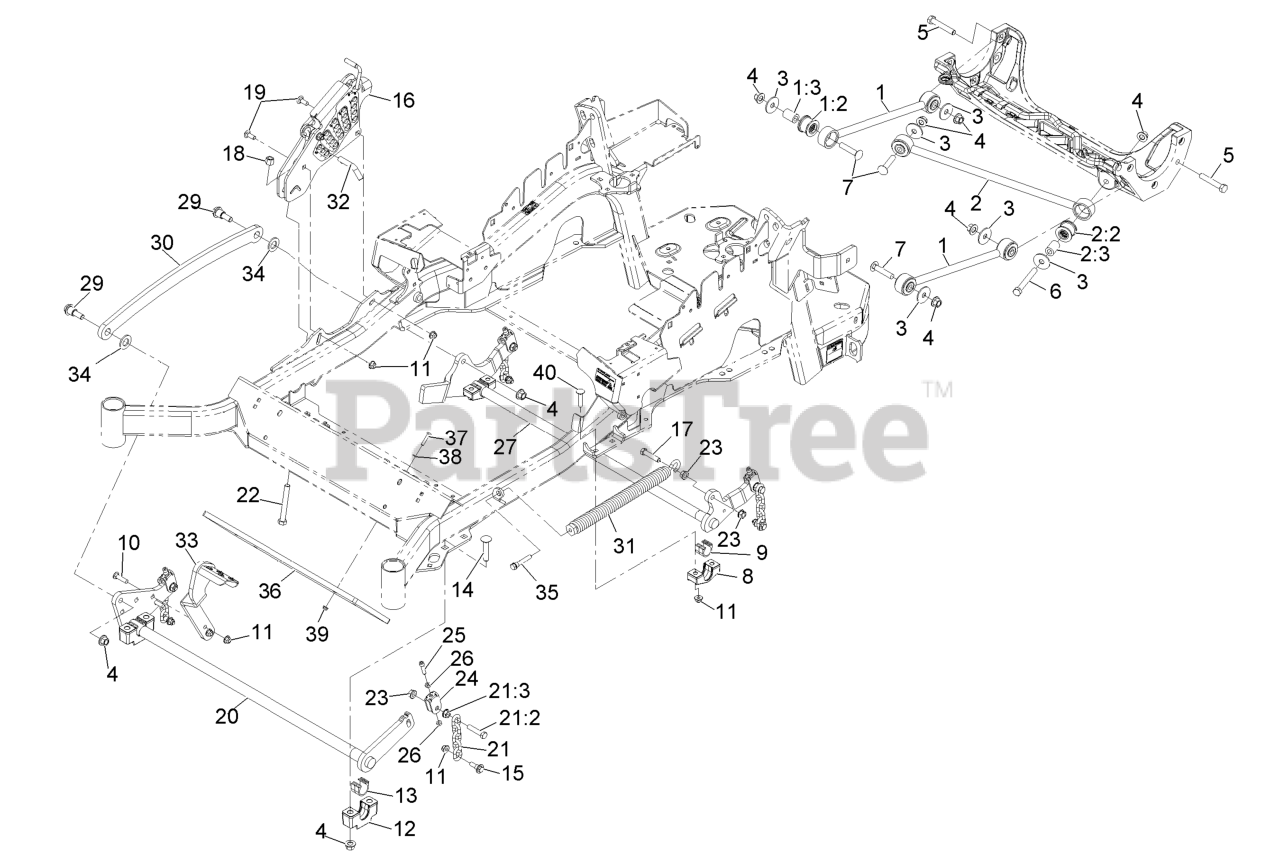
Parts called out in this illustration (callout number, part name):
1	DECK STRUT ASM
1:2	BUSHING-SUSPENSION, RUBBER
2	PANHARD ROD ASM
2:2	BUSHING-SUSPENSION, RUBBER
3	WASHER-THRUST
4	Nut-Lock 1/2-13
5	SCREW-HH
6	SCREW-HH
7	SCREW-CARR
9	BEARING-CROSS SHAFT, REAR
10	SCREW-CARR
11	NUT-HF, NI
12	SUPPORT-CROSS SHAFT, BEARING
13	BEARING-CROSS SHAFT, FRON
14	Bolt-Carriage 1/2-13 X 2 1/2 Spl Neck
15	SCREW-SHOULDER, HHF
16	HOC ASM
17	SCREW-HH
18	NUT-LOCK, NI
19	BOLT-CARR
21	DECK LIFT CHAIN ASM
21:2	SCREW-HH
22	BOLT-TAP
24	YOKE-ADJUST, DECK
25	SCREW-HSH
26	NUT-JAM
27	LIFT-DECK, REAR
29	SCREW-SHOULDER, HHF 1/2-13 X 1.12
30	LINK-LIFT, DECK
31	SPRING-EXTENSION
32	PIN-HOC
33	LEVER-FOOT
34	WASHER-FLAT
35	BOLT-SHOULDER
36	WEIGHT,TOE BOARD
37	SCREW-HH
38	WASHER-FLAT
40	SCREW-CARR
